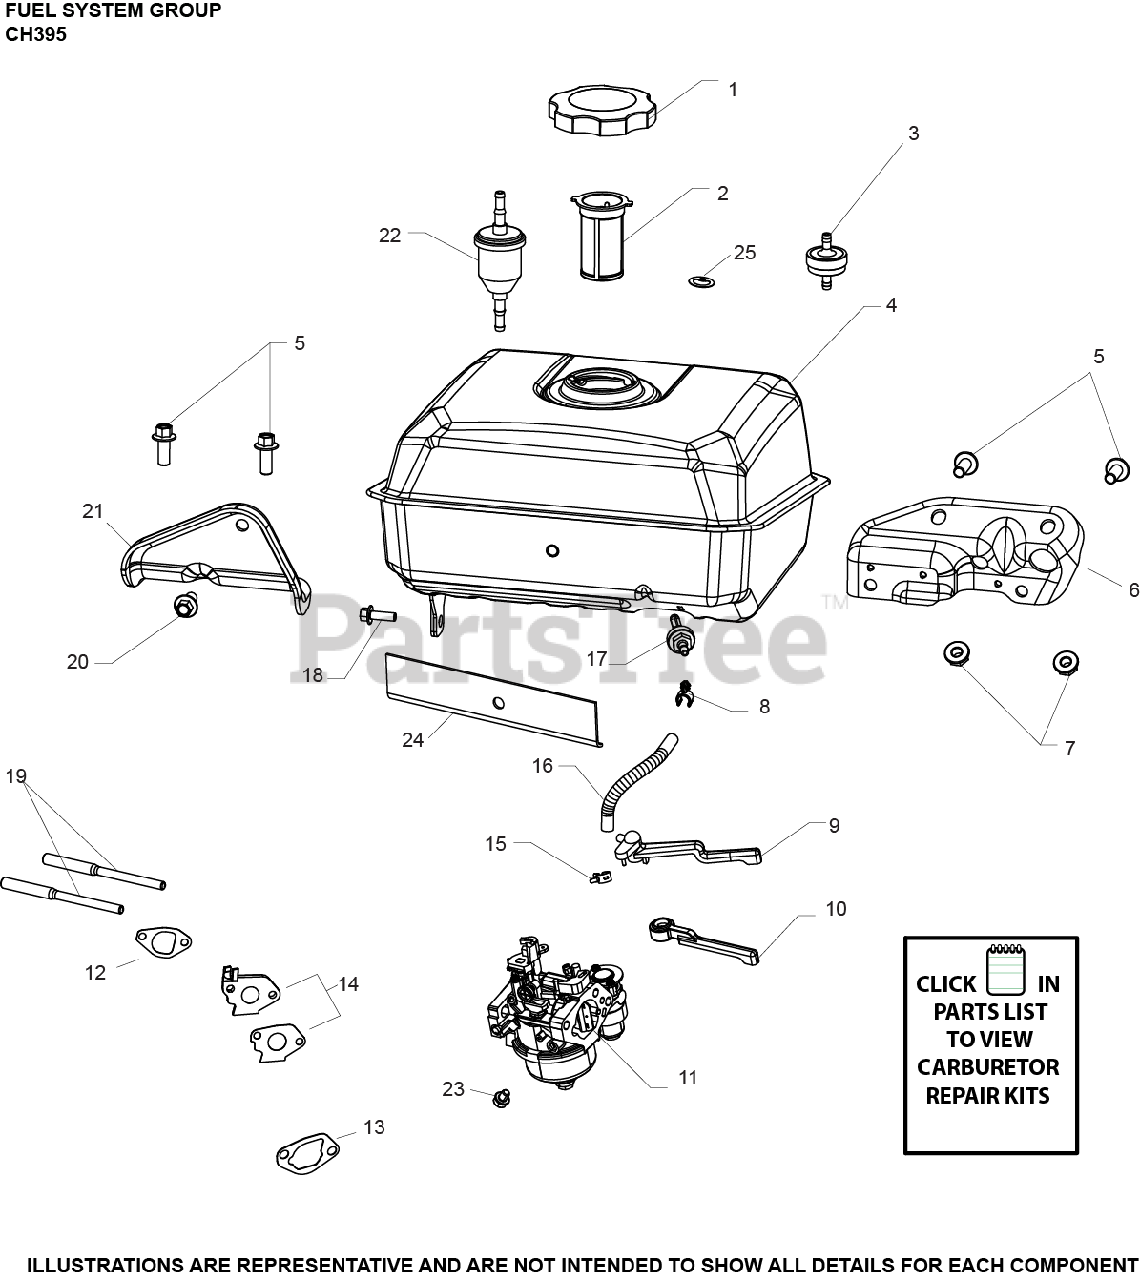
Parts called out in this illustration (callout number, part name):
5	SCREW, M8 X 20
11	KIT, CARBURETOR USE 17 853 95-S
14	INSULATOR AND GASKET KIT
15	CLAMP, FUEL LINE
16	LINE, FUEL (10"-CUT TO LENGTH)
19	STUD, INTAKE
